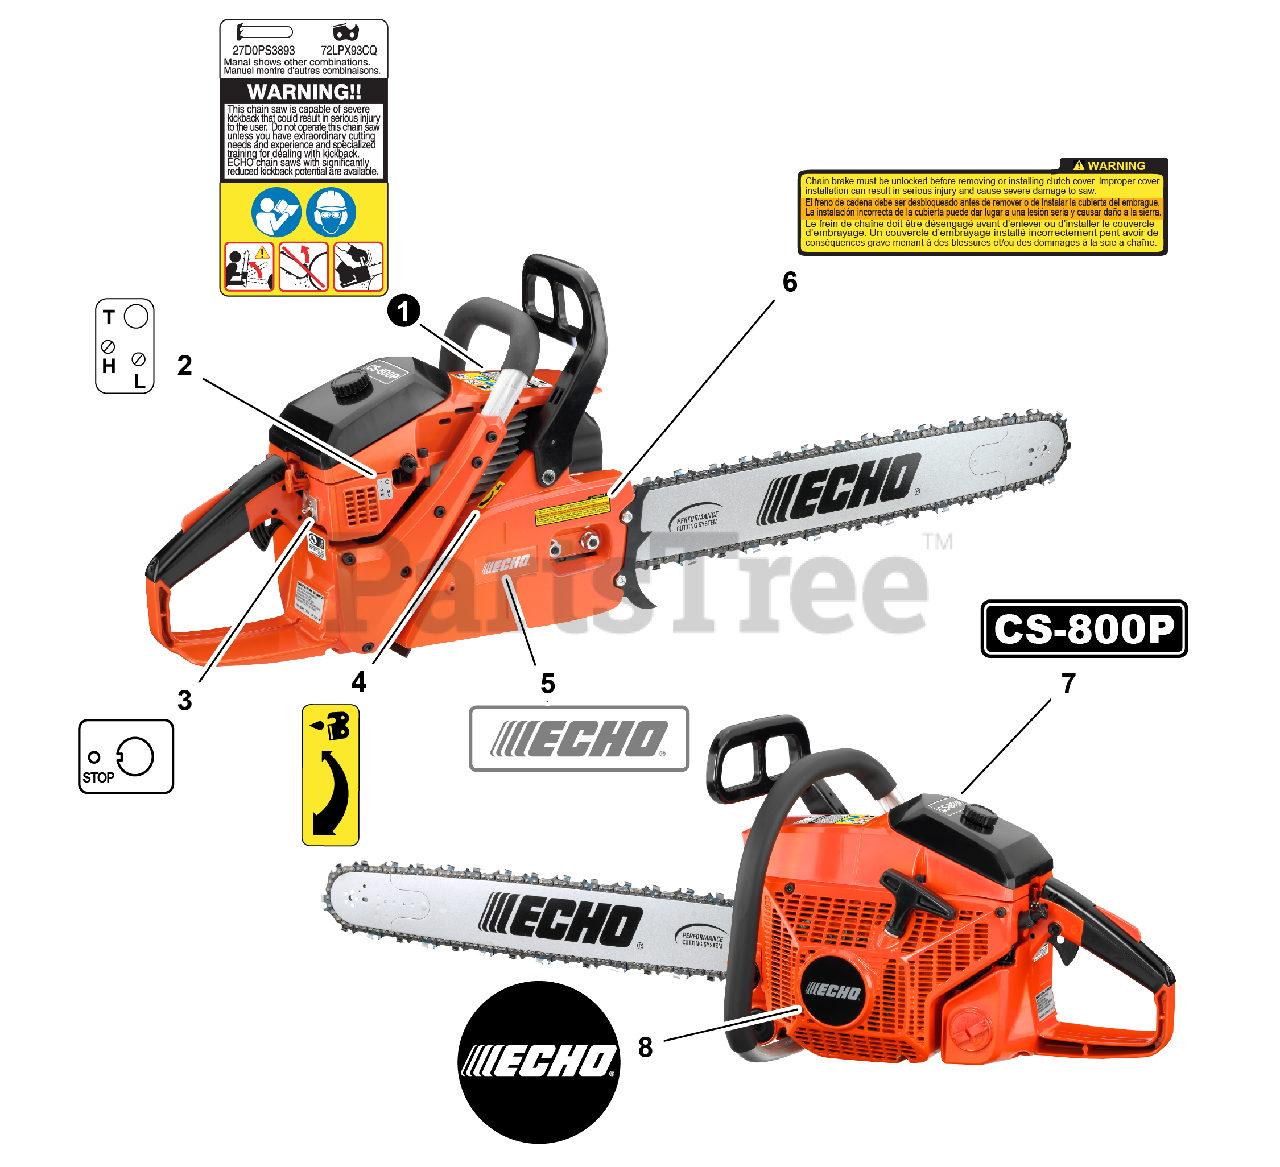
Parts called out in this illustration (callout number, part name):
1	LABEL, CAUTION
3	LABEL, STOP
4	LABEL, OILER
5	LABEL, ECHO
6	LABEL, WARNING
7	LABEL, CS-800P
8	LABEL, RECOIL STARTER
